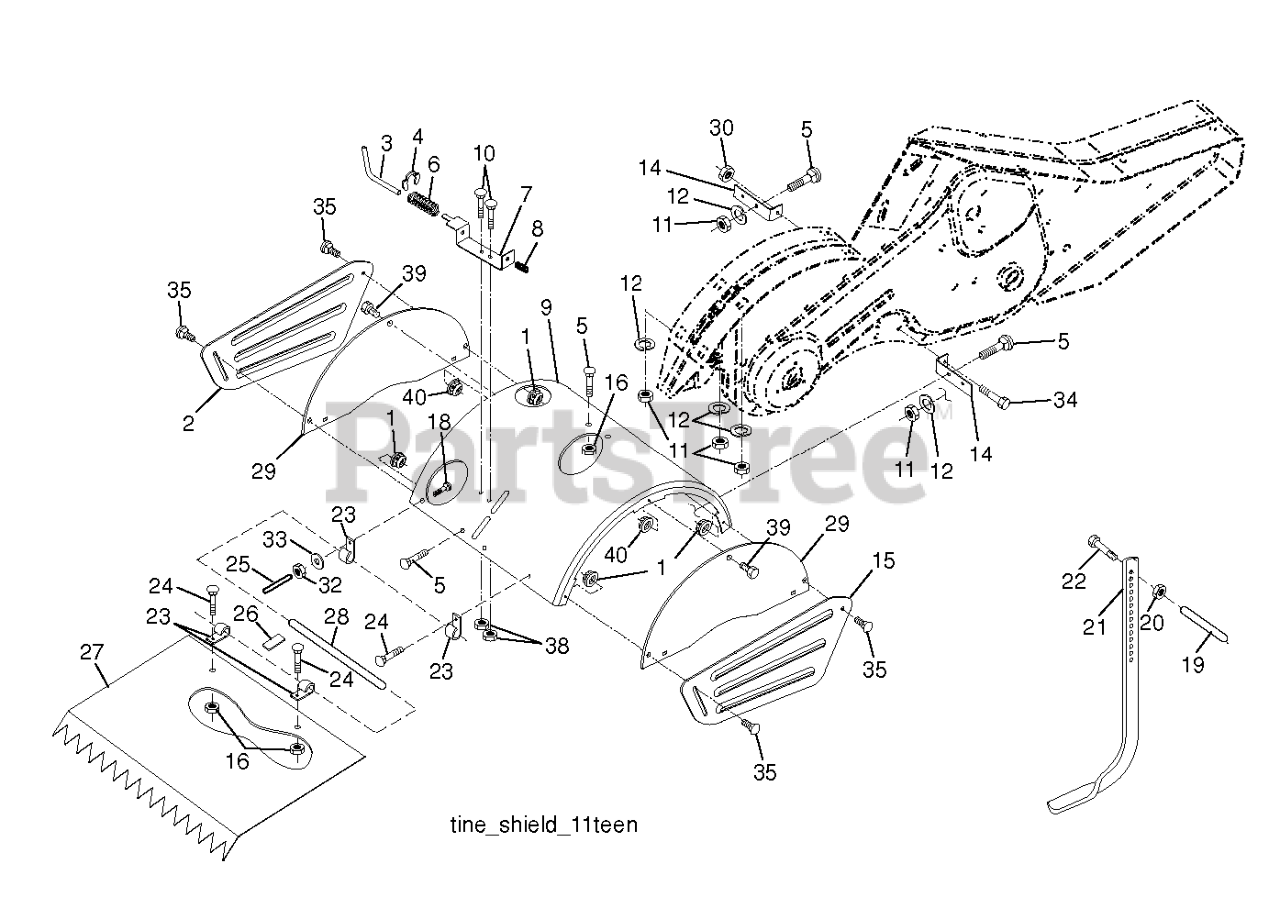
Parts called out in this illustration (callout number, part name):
1	NUT.FLANGE.5/16
2	SHIELD.SIDE.OUTER.LH.ORANGE
3	STAKE PIN TI
4	RING, KLIP
5	BOLT, RDHD SQNK 5/16-18 X 3/4
7	BRACKET
8	SPRING CRT
9	SHIELD.TINE.TILLER.ORANGE
12	WASHER.LOCK.HVY.HLCL.SPR.5/16
14	BRACKET.TINE.SHIELD.BLACK
15	SHIELD.SIDE.OUTER.RH.ORANGE
16	NUT T
20	NUT.HEX.3/8-16UNC
21	STAKE.DEPTH.ASM.CRT 19/21.BLAC
22	BOLT.375-16
25	VINYL CAP TI
26	PAD IDLER TI
27	SHIELD.PNT.LEVELING.ORANGE.668
28	PIN, HINGE
29	SHIELD.SIDE.66
30	LOCKNUT-FLANGE 5/16-18
32	NUT
33	LOCKWASHER
34	Bolt Hex Flanged 5/16-18 Unc x 2
35	BOLT.CARR.5/16-18X5/8.SHORT
38	NUT
39	BOLT.HEX.HD.WASHER.5/16-18X.75
40	NUT.SPEED.5/16-18
